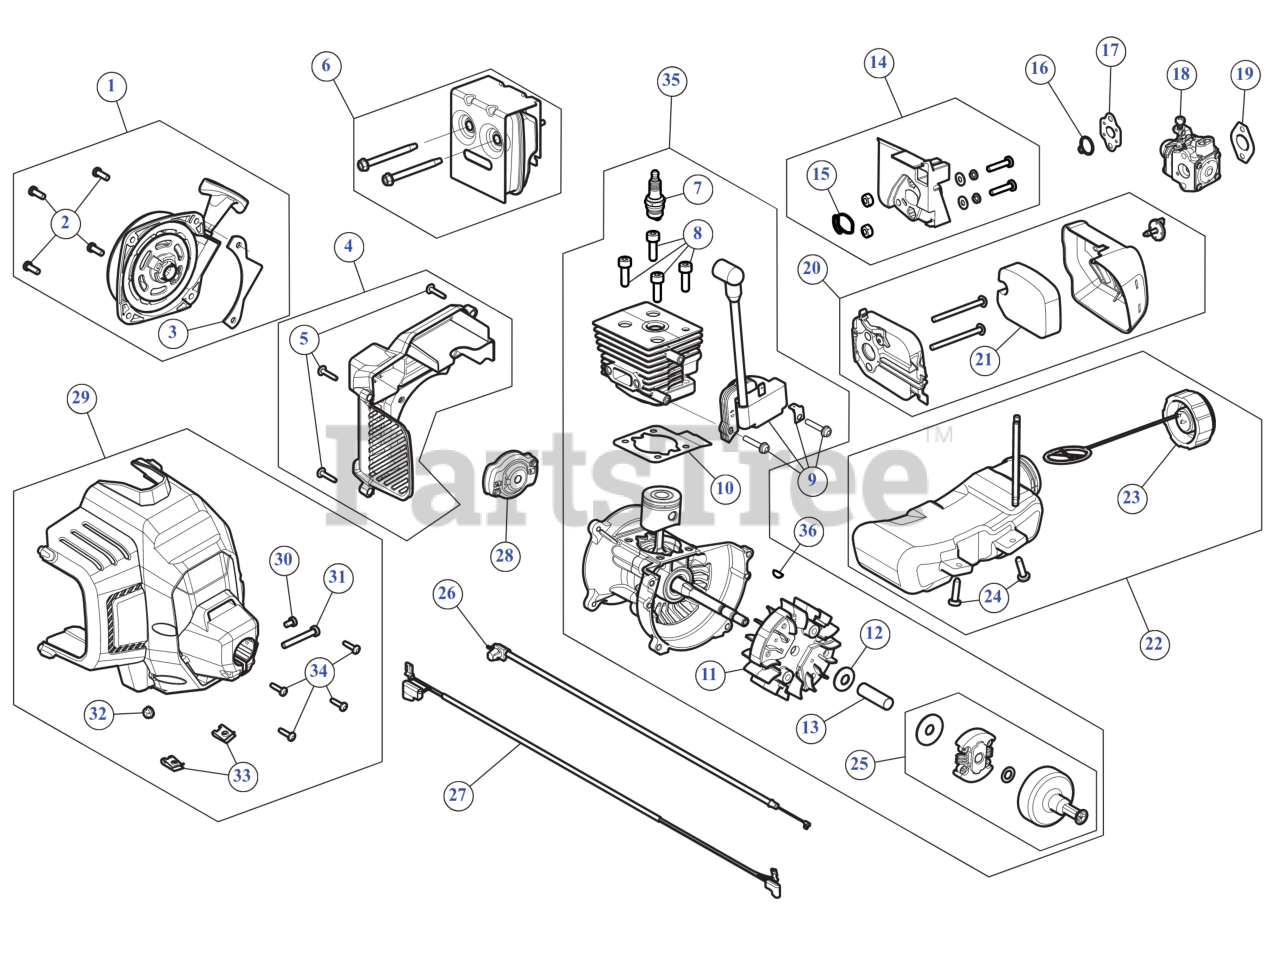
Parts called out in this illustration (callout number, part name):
1	STARTER ASSEMBLY
2	SCREW:10-32X.562:#8P
3	STARTER GUARD
4	REAR ENGINE COVER
5	SCREW 8-16 x 3/4
6	MUFFLER ASSEMBLY
7	SPARK PLUG
8	SCREW 1/4 x 20 x .8125
9	MODULE 27CC DIG
10	GASKET CYL
11	FLYWHEEL ASSEMBLY 27CC
12	BELL WASHER
13	SPACER
14	INTAKE ASSEMBLY
15	O-RING
16	O-RING
17	CARBURETOR GASKET
18	CARBURETOR
19	GASKET CARB
20	AIR CLEANER
21	AIR FILTER
22	FUEL TANK ASSEMBLY
23	FUEL CAP
24	SCREW:10-6 x .75
25	SMALL CLUTCH ASSEMBLY W/SMALL DRUM
26	THROTTLE CABLE
27	LEAD WIRES
28	PAWL ASSEMBLY AC5
29	CLUTCH COVER
30	SCREW, 8-32 x .312 P
31	SCREW
32	HEX NUT
33	NUT, TINNERMAN U-T
34	SCREW #10-24X11/16 T-25
35	SHORTBLOCK
36	WOODRUFF KEY #403-.125 x .375
